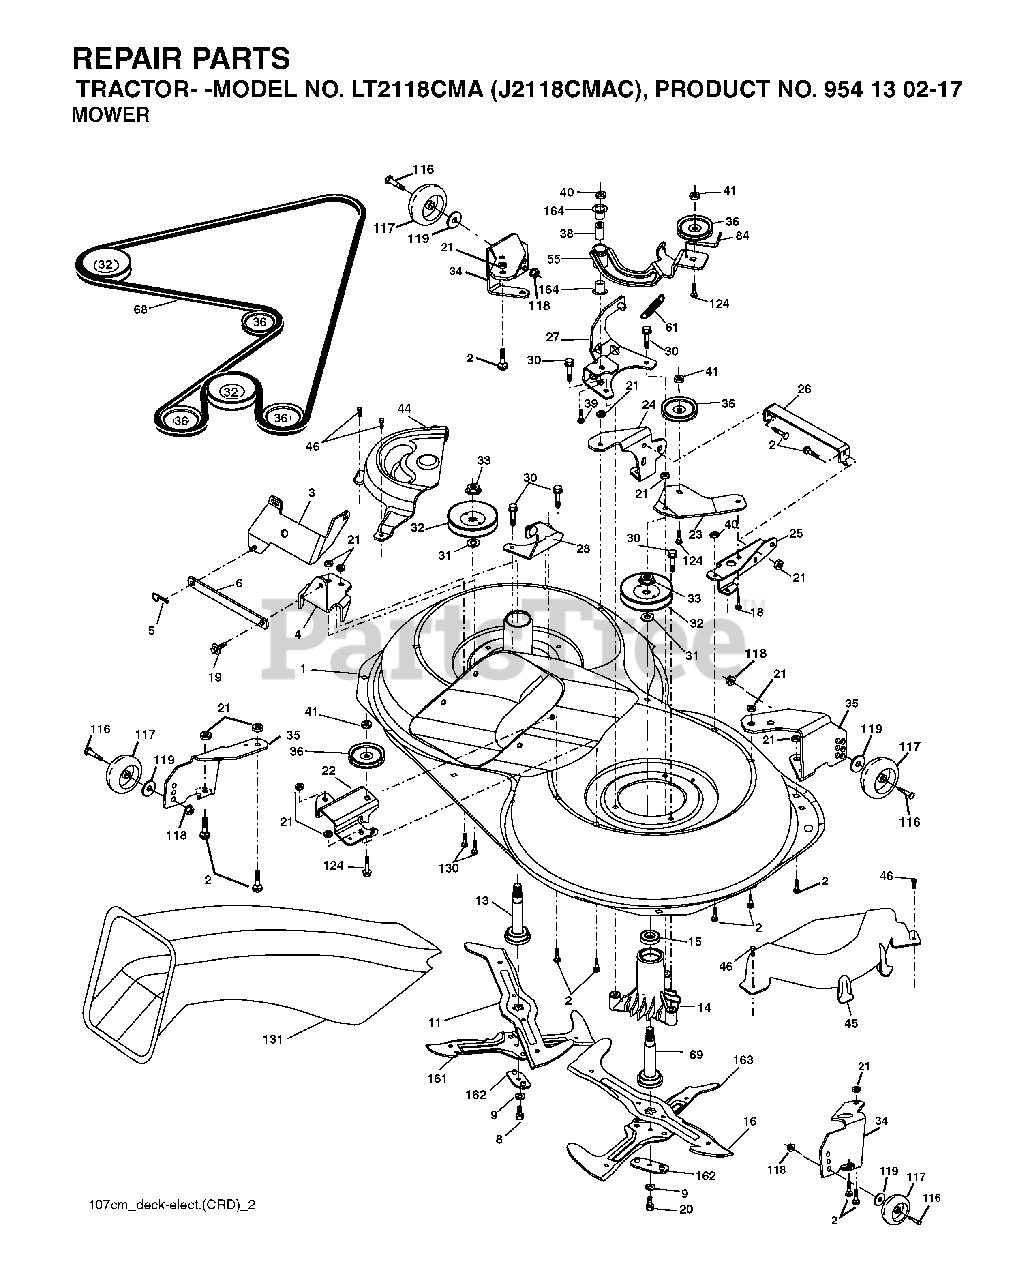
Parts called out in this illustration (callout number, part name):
2	BOLT
3	BRACKET
5	RETAINER-SPRNG RB
6	BAR SWAY
9	LOCKWASHER
11	BLADE.3N1.LH.CRD
13	SHAFT ASM VENT
14	HSG MANDREL
16	BLADE.3N1.RH.CRD
19	BOLT SHD 5/16-18
21	LOCKNUT
22	BRACKET
23	BRACKET
26	BRACE
27	BRACKET
30	SCREW, WASHER HEAD
31	WASHER.SPACER.MANDREL
33	NUT, FLG TOPLOCK 9/16"
36	PULLEY.IDLER.4.25
40	LOCKNUT
41	NUT LOCK FLG 3/8-16 UNC
45	MANDREL COVER
46	SCREW.1/4-20X5/8
55	ARM IDLER
68	HEX-BELT 107 MOWER
69	SHAFT.ASM.W/LWR.BRG.RH.THREAD
84	KEEPER, BELT IDLER
116	SHOULDER BOLT
117	WHEEL GAGE DONUT
118	LOCKNUT
119	WASHER
124	BOLT.3/8-16X1.50
131	CHUTE BAGGER
164	BRNG T
